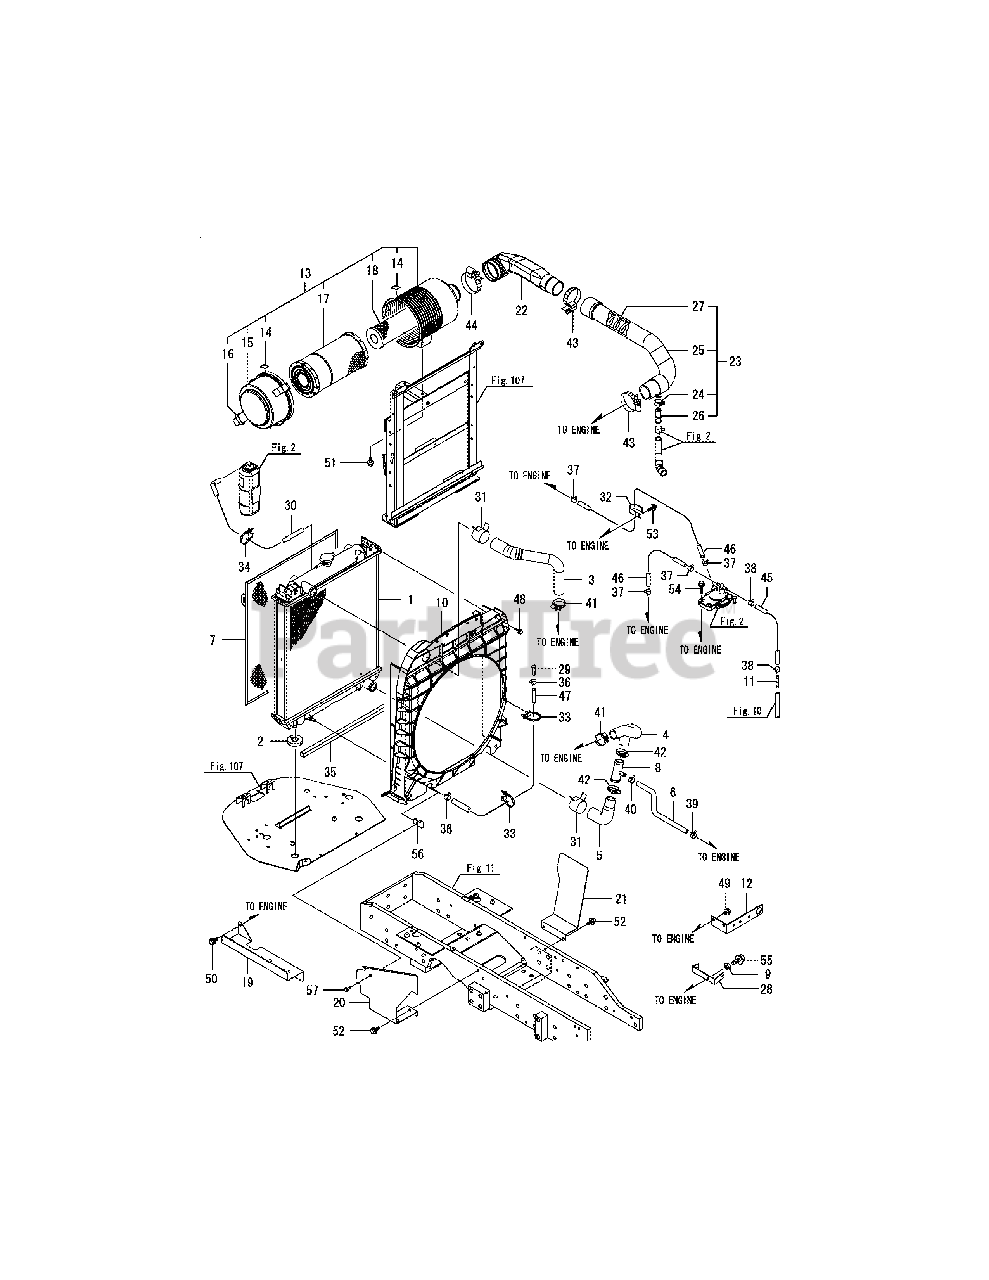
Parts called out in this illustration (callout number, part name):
2	RUBBER,RADIATOR
3	TUBE,COOLING WATER A
4	PIPE, COOLING WATER
5	PIPE, COOLING WATER
6	CW-T, LO COOLER OUT
7	SCREEN, RADIATOR
8	JOINT, WATER COOLING
10	SHROUD M ASSY, FAN
12	CLAMP, FUEL HOSE
13	CLEANER ASSY, 6IN D
16	VALVE, UNLOADER
18	ELEMENT, INNER
19	PLATE,SHUTTER,84T
23	HOSE ASSY, INTAKE B
25	HOSE, INTAKE B
26	JOINT, BREATHER
28	BRACKET, CLAMP
30	PIPE, C. WATER
32	CLAMP, WIRE HARNESS
35	URETHANE,SIDE LAMP
45	HOSE 7.3X200,BRAIDED
46	FUEL PIPE 7.3X400
47	FUEL PIPE 7.3X600
48	BOLT M 6X 20 PLATED
49	BOLT M 8X 12 PLATED
50	BOLT M 8X 12 PLATED
51	BOLT M 8X 16 PLATED
52	BOLT M 8X 16 PLATED
53	BOLT M 8X 16 PLATED
54	BOLT M 8X 30 PLATED
55	BOLT M10X 20 PLATED
57	BOLT M 6X 20 PLATED
